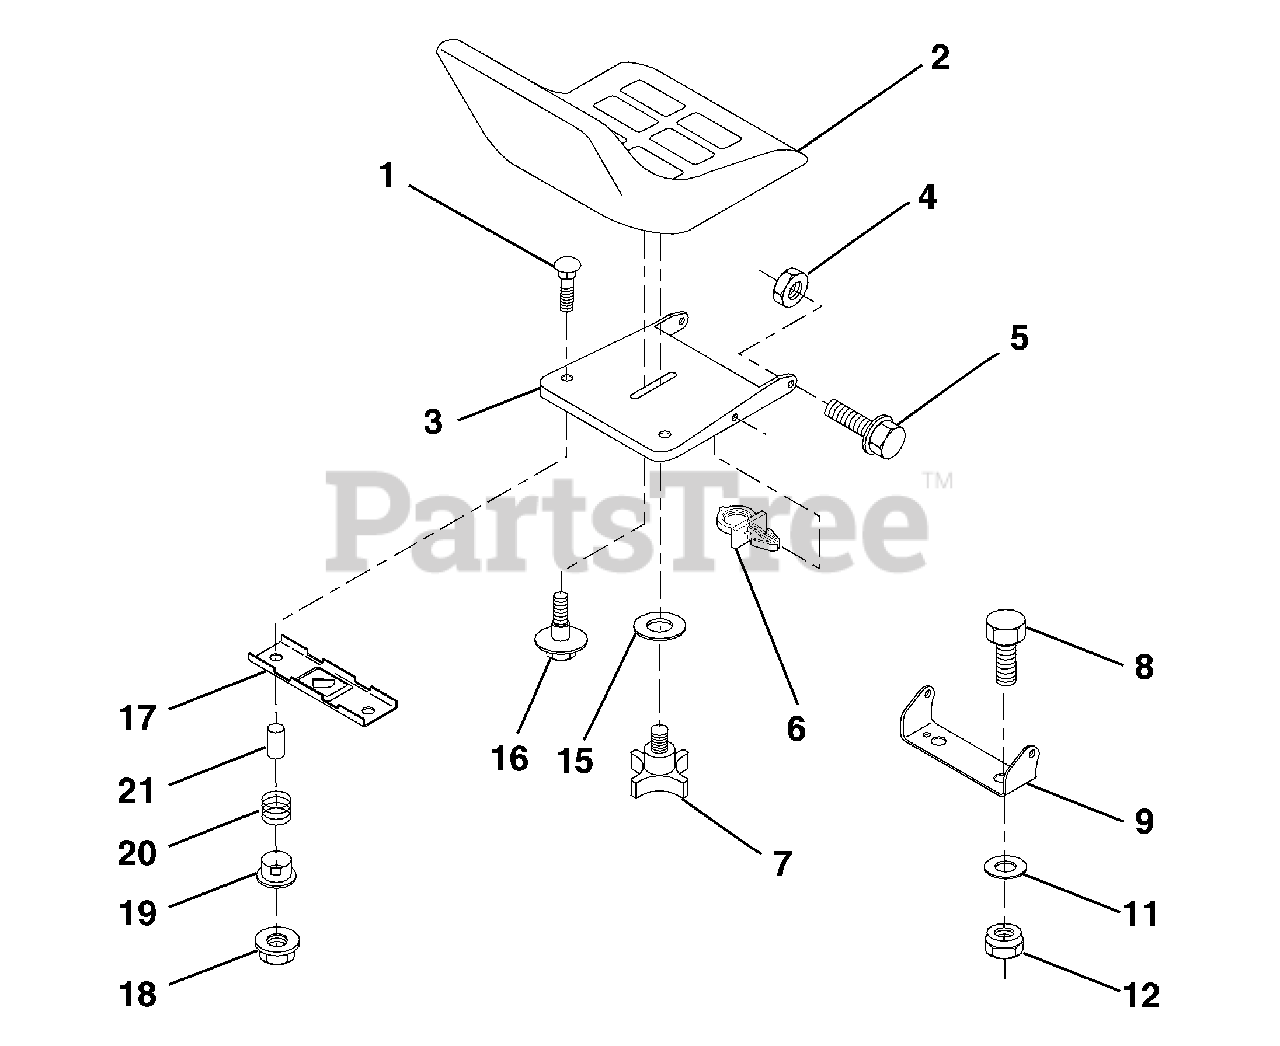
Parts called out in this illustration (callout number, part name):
1	Bolt, Carriage 1/4-20 x 1-3/8
2	Seat
3	Pan, Seat
4	Nut Lock Hex W/Ins 5/16-18
5	Bolt, Shoulder 5/16-18 UNC
6	Clip, Push-In
7	Knob, Seat
8	Bolt, Hex, Fin. 3/8-16 UNC x 1
9	Bracket, Pivot, Seat
11	Washer 12/32 x 2 x 10 Gauge
12	Nut Lock Hex W/Wsh 3/8-16
15	Washer 17/32 x 1-3/16 x 12 Gauge
16	Bolt, Shoulder
17	Bracket, Switch Mounting
18	Nut, Hex, Large, Flange Lock
19	Bushing, Snap
20	Spring, Compression
21	Spacer, Split, Large .28 Id. x .96
